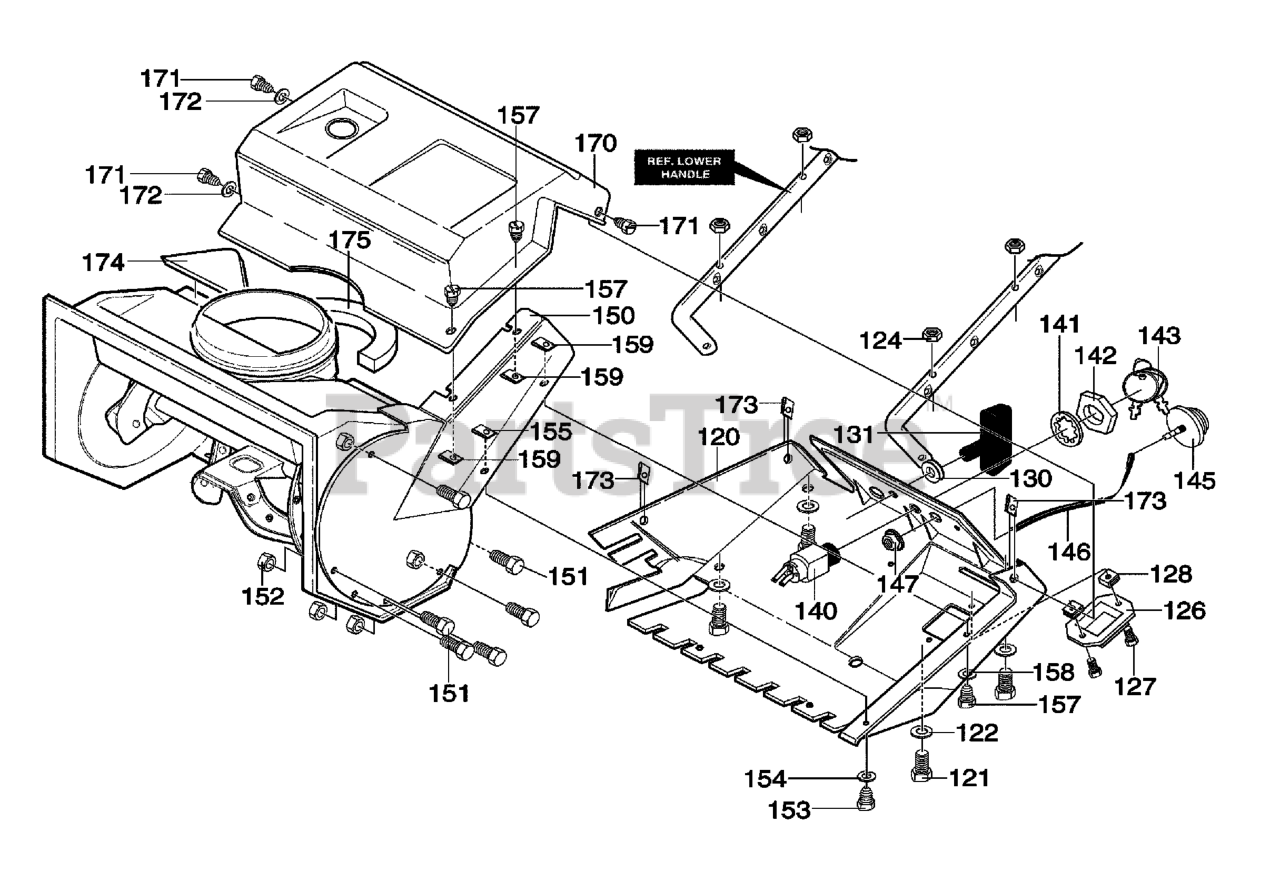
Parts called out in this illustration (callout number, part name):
120	COVER, BOTTOM
121	SCREW, 1/4-20X1.25
122	WASHER, FLAT .281X.63X.065
124	NUT, 1/4-20 REGHEXCTRLK
126	COVER, CARB
127	SCREW, 1/4-14X.75
128	NUT, 1/4-10 SPEED J TYPE
130	GROMMET & WASHER, ROPE GUIDE
131	KNOB, STAND TEE
140	SWITCH, IGNITION
141	WSHER, REGINTLK
142	NUT, 5/8-32 ACC
143	2 KEYS & RING
145	PRIMER, ENGINE
146	HOSE, PRIMER
147	NUT, 1/4-20 REGHEXKEPS
150	COVER, BELT
151	SCREW, 10-24X.50 WAHHMA
152	NUT, #10-24 REGHEXCTRLK
153	SCREW, 1/4-20X.50
154	WASHER, FLAT .281X.63X.065
155	NUT, 1/4-20 TINN
157	SCREW, 1/4-14X.75 SLWATAP
158	WASHER, FLAT .281X.63X.065
159	NUT, 1/4-20 SPEED J TYPE
170	COVER, TOP
171	SCREW, 1/4-14X.75 SLWATAP
172	WASHER, FLAT .281X.63X.065
173	NUT, 1/4-10 SPEED J TYPE
174	SEAL, STRIP AUG HSING FOAM
175	SEAL, STRIP CHUTE & GAS SEAL
